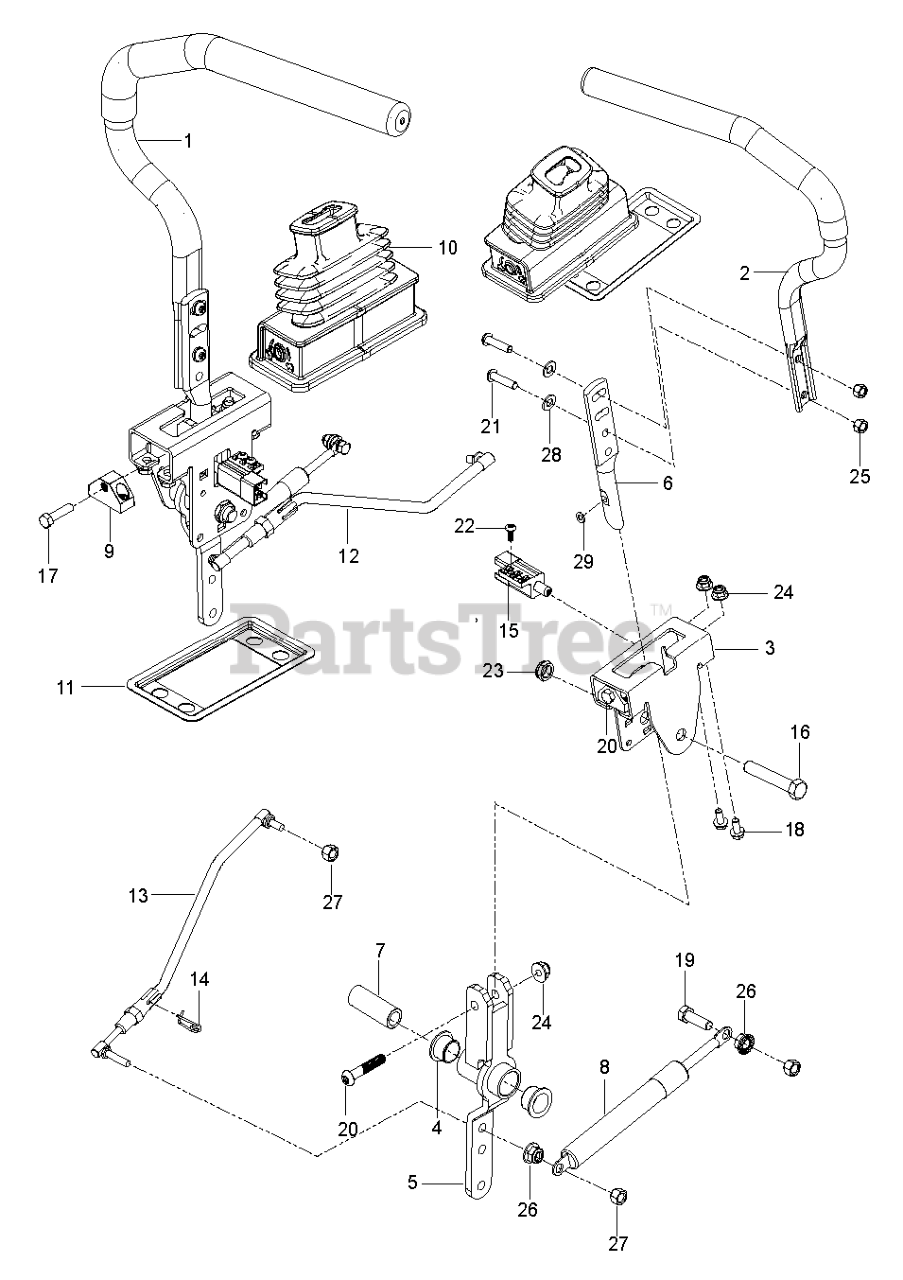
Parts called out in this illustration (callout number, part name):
1	TUBE.LEVER.CNTL.ASM.ZTR.RT.SVC
2	TUBE.LEVER.CNTL.ASM.ZTR.LT.SVC
3	BRACKET.CONTROLS.ZTR.X431
4	BEARING, FLANGE
5	LEVER CONTROL PIVOT
6	CONTROL.LEVER.HANDLE
7	SPACER.PIVOT.CONTROL
9	BLOCK TRACKING CONTROL ZTR
10	BOOT.STEERING.LEVER
11	CONTROL.BOOT.FLANGE.X431
12	ROD.ASM.RH.ADJUSTABLE
13	ROD.ASM.LH.ADJUSTABLE
14	RETAINER.CLIP.SPRING.S
15	SWITCH.INTLK.RZ.RFRSH.BUTTON
16	HCS 1/2-13 X 2-3/4 GD 5 ZD
17	SCREW.SHAKEPROOF.1.25.BLACK
18	HHFS 5/16-18 X 3/4
19	HCS 5/16C X 1
20	SCREW.CAP.SOCKET.6PT.5/16-18
21	BUTTONHEAD.5/16-18X1.125.BLACK
22	SCREW.BUTTONHD.10-24X1/2.(2 2)
23	NUT 1/2-13 HEX JM NYL
24	5/16-18 NYLOC FLANGE NUT
25	NYLOCK.NUT.5/16-18 BLACK
26	NUT 5/16C WHIZ
27	NUT.71038.31-18.HEX.NYLOCK
28	WASHER
29	WASHER.11/32ID.11/16OD.116THIC
